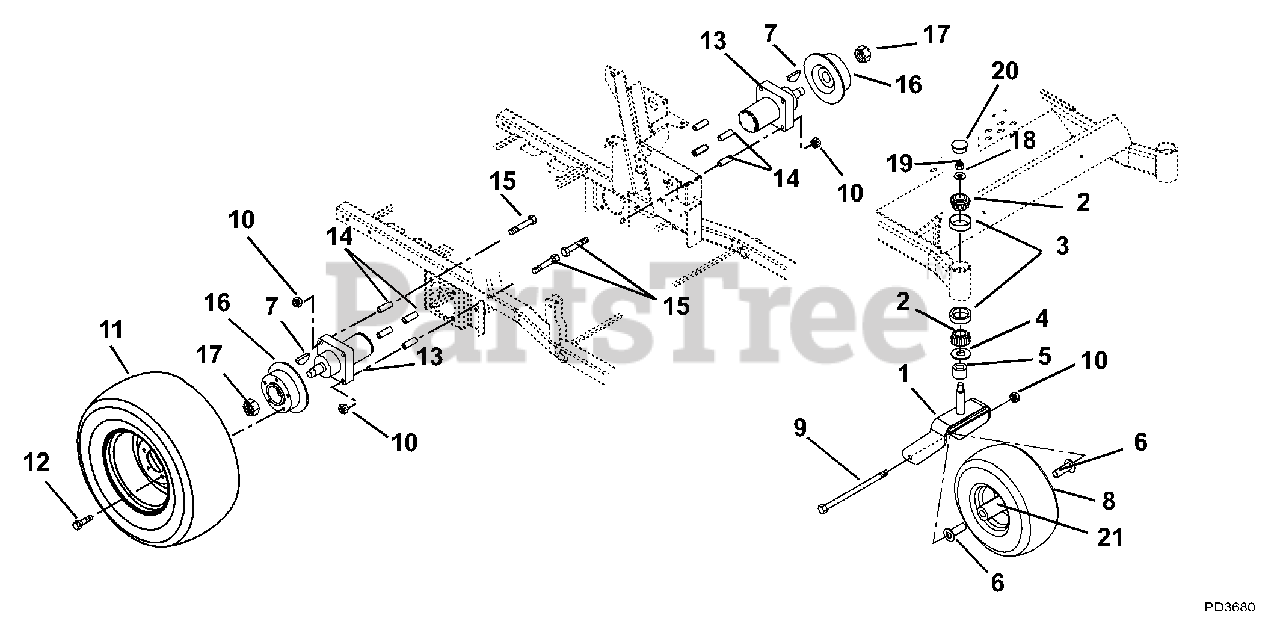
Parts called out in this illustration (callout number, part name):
1	Fork
2	Bearing, Cone with Grease
3	Bearing, Cup 1.98 x .420
4	Bearing Seal 1.5 x 2 x .18
5	Spacer, PM, 1.03 I.D. x 1.5 O.D. x .375
6	Spacer, Wheel
7	Key, Woodruff .31 x 1.00
8	Wheel/Tire Assembly
8	Tire, 15 x 6-6
9	Bolt, Hex .50-13 x 9.00 Grade 5
10	Nut, Locking Top Flange .50-13
11	Wheel, Tire Assembly 23 x 10.50 -12
11	Tire 23 x 10.50
11	Wheel, Tire 23 x 10.50 - 12 Multi-Trac
12	Bolt, Lug Grade 8 .50-20 UNF x 1.38 Long 60 Degree
13	Hydraulic Wheel Motor
14	Bushing, Sleeve .513 x .748 x 2.13
15	Bolt, Wheel Motor .50-13 x 5.00
16	Hub and Disc
17	Nut, Lock Jam Patch
18	Washer, Flat, Steel .812 x 1.50 x .135
19	Nut, Jam Center Lock .75-16
20	Cap, Dust
21	Bearing, 25mm I.D. x 52mm OD x 15mm
